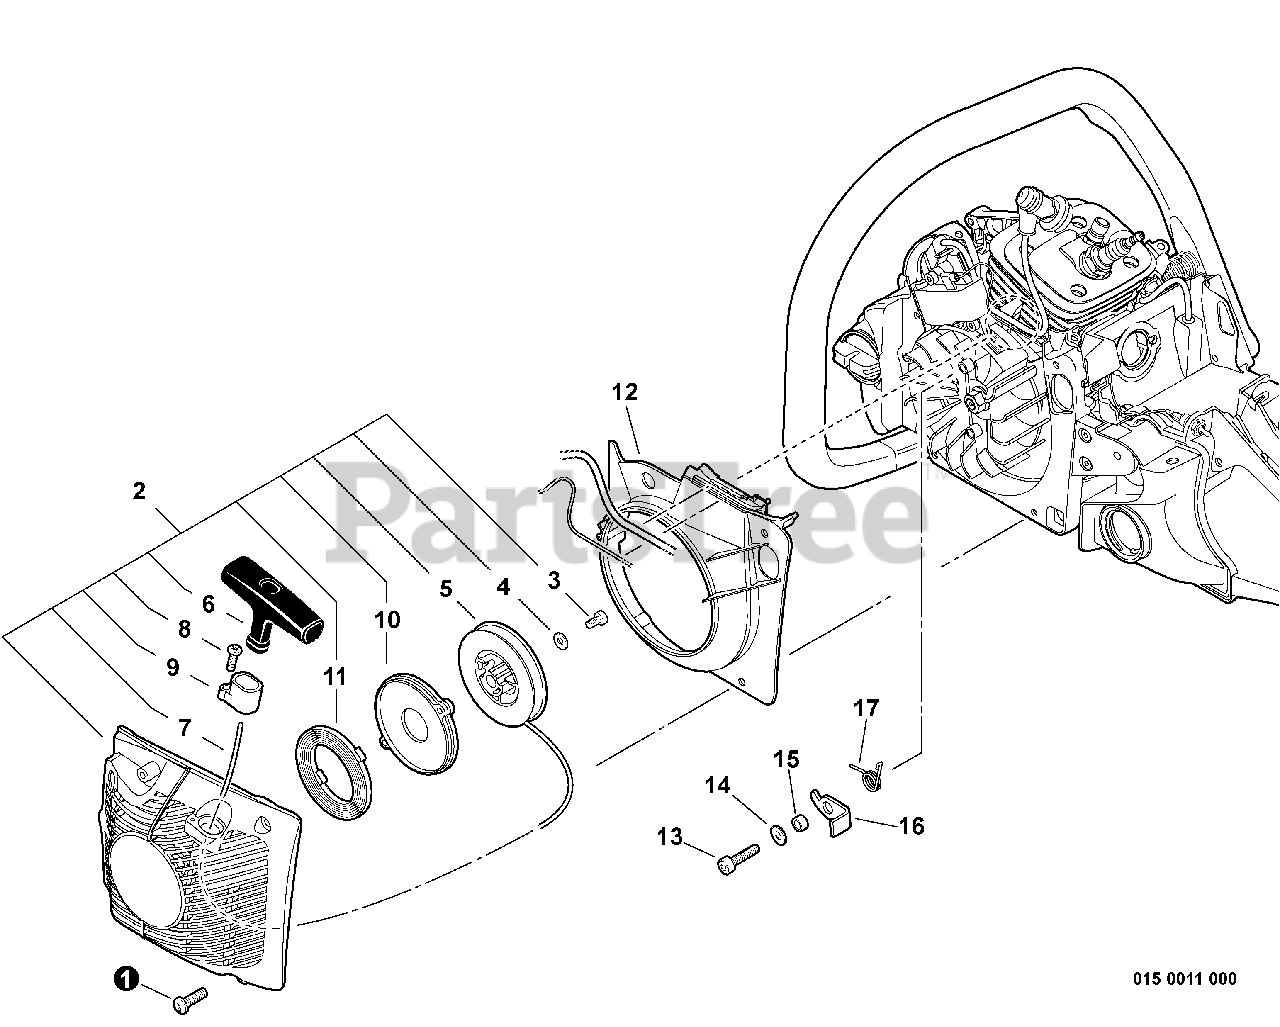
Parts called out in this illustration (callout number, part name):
1	SCREW - 5X20
2	STARTER ASSY
3	SCREW - 5X10
4	WASHER - 5
5	REEL, ROPE
6	GRIP, STARTER
7	ROPE, STARTER - 4X950
8	SCREW - 3X16 -- TAPPING
9	GUIDE, ROPE
10	PLATE, STARTER
11	SPRING, REWIND
12	COVER, FAN
13	SCREW - 5X16
14	WASHER - 5
16	PAWL, STARTER
17	SPRING, RETURN
